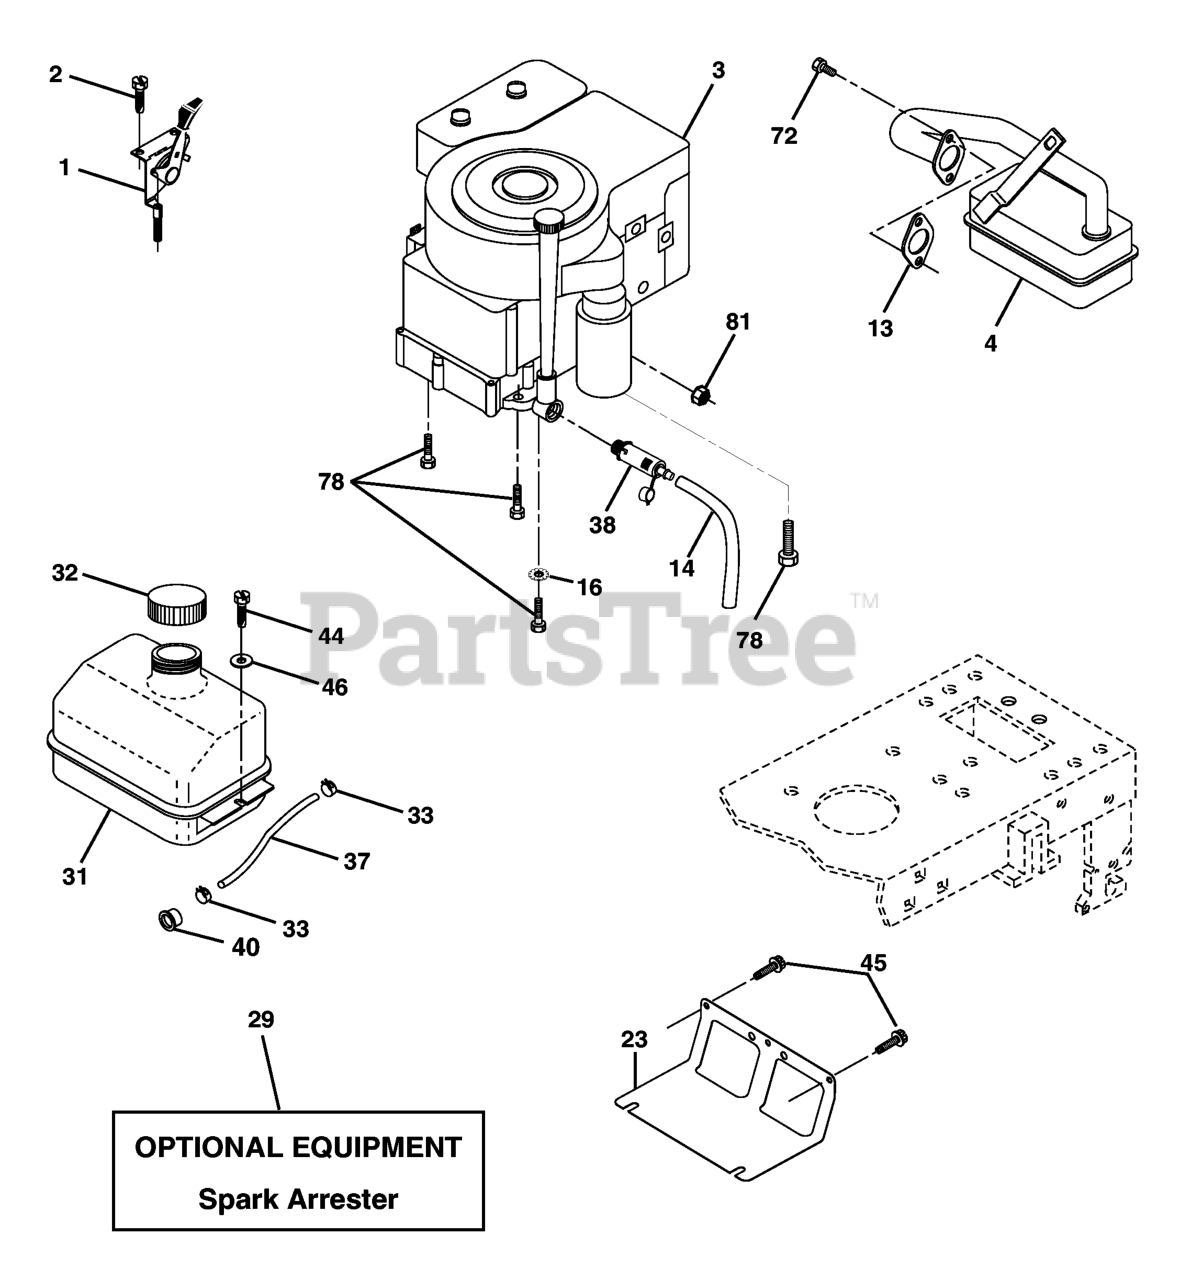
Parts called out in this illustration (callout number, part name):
1	CHOKE CONTROL
2	SCREW LT
4	MUFFLER.SINGLE.B&S.10-12HP
13	GASKET.ENG.1.313 ID.TIN PLATED
14	Nipple Pipe 3/8 Npt X 3"
15	ELBOW
16	LOCKWASHER
29	KIT.SPARK ARRESTOR 794945 B&S
31	TANK FUEL LT
32	FUEL CAP
33	HOSE CLAMP
35	SCREW.THDROL.5/16-18X3/4.TTY
37	LINE.FUEL.20
38	Oil Drain Plug
40	BUSHING.SNAP.NYL.BLK.
44	SCREW HEX CRT
46	WASHER
62	WASHER.LOCK.HVY.HLCL.SPR.5/16
72	SCREW
